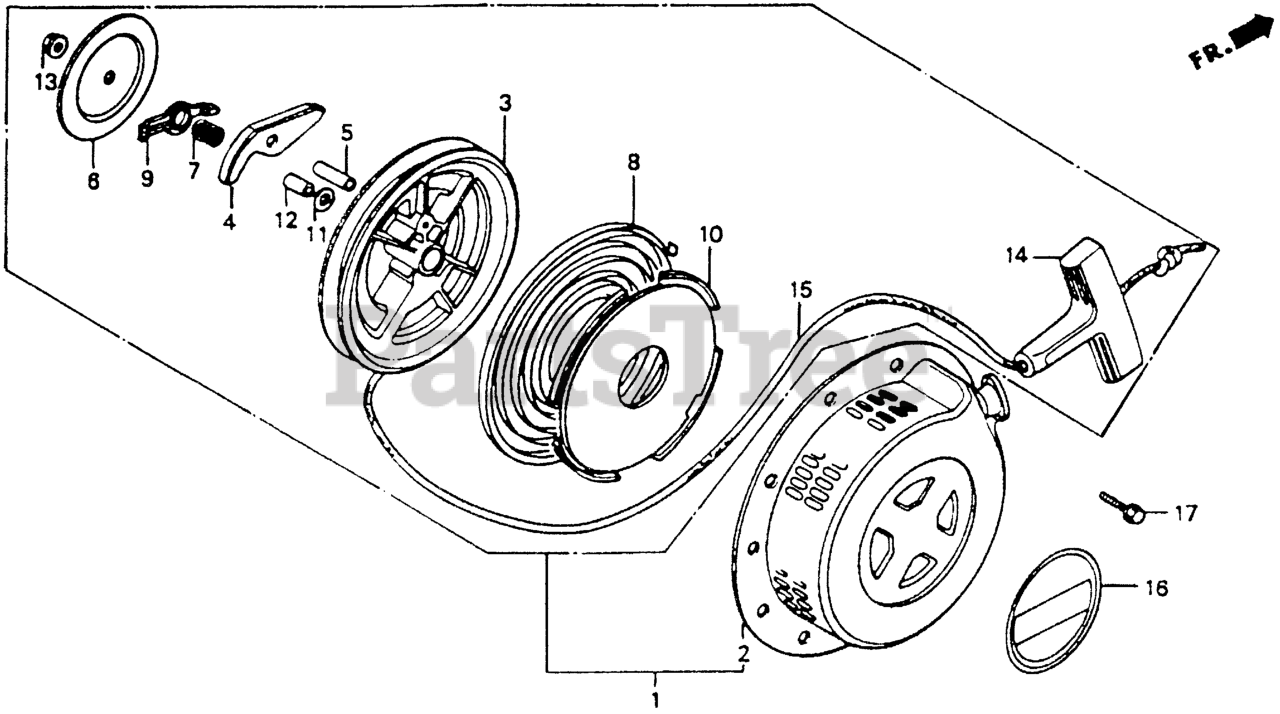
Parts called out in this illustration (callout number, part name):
1	STARTER ASSY., RECOIL *R280* (POWER RED)
2	CASE, RECOIL STARTER *R8* (BRIGHT RED)
3	PULLEY, RECOIL STARTER
4	RATCHET, STARTER
5	PIN, STARTER RATCHET
6	PLATE, FRICTION
7	SPRING, FRICTION
8	SPRING, RECOIL STARTER
9	GUIDE, RATCHET
10	CASE, RECOIL STARTER SPRING
11	WASHER, STARTER
12	SHAFT, SUB
13	NUT
14	KNOB, RECOIL STARTER
15	ROPE, RECOIL STARTER (#5X59") (NA USE ALT:08550-ZG921-11)
16	EMBLEM (EXTERNAL)
17	BOLT, FLANGE (6X8)
